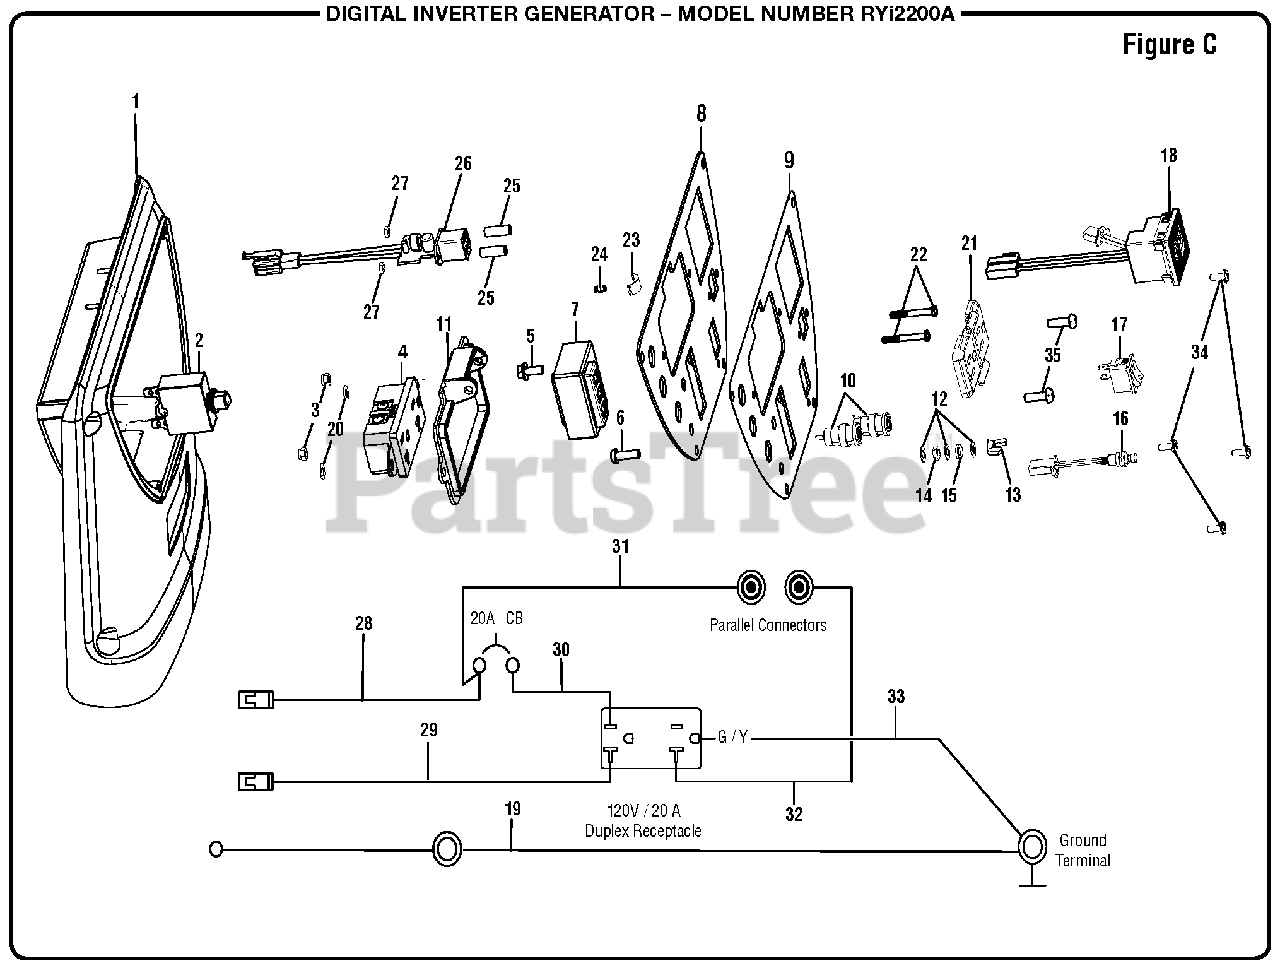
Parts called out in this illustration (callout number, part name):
1	Front Cover w/Labels & Foam
2	Circuit Breaker (20A)
3	Hex Nut (M4)
4	120 Volt Duplex Receptacle (20 Amp)
5	Bolt (M5 x 12 mm, Flange Hex Hd.)
6	Screw (M5 x 16 mm, Pan Hd.)
7	Ignition Module
8	Control Panel
9	Front Panel Label
10	Connector (Black)
11	Receptacle Cover (Back)
12	Washer (OD10 x ID5.3 x 0.5t)
13	Wing Nut (M5)
14	Hex Nut (M5)
15	Lock Washer (OD9 x ID5 x 1.3t)
16	Reset Button
17	Auto Idle Switch
18	12V DC Receptacle
19	Wire Lead (14AWG-220 mm, Yellow-Green)
20	Washer (OD10 x 4.2 x 1t)
21	Receptacle Cover (Front)
22	Screw (M3 x 25 mm, Pan Hd.)
24	Compression Spring
25	Spacer (17.2 mm)
26	Circuit Board (USB Port Charger)
27	Hex Nut (M3)
28	Wire Lead (14 AWG-220 mm)
29	Wire Lead (14 AWG-220 mm w/Dj441-4B)
30	Wire Lead (14 AWG-110 mm w/Dj441-4B)
31	Wire Lead (14AWG-80 mm)
32	Wire Lead (14AWG-110 mm w/Dj622-D6-3B)
33	Wire Lead (14AWG-120 mm)
34	Screw w/Washer (M4 x 10 mm, T20 Torx Button Hd.)
35	Screw (M4 x 14 mm,Pan Hd.)
